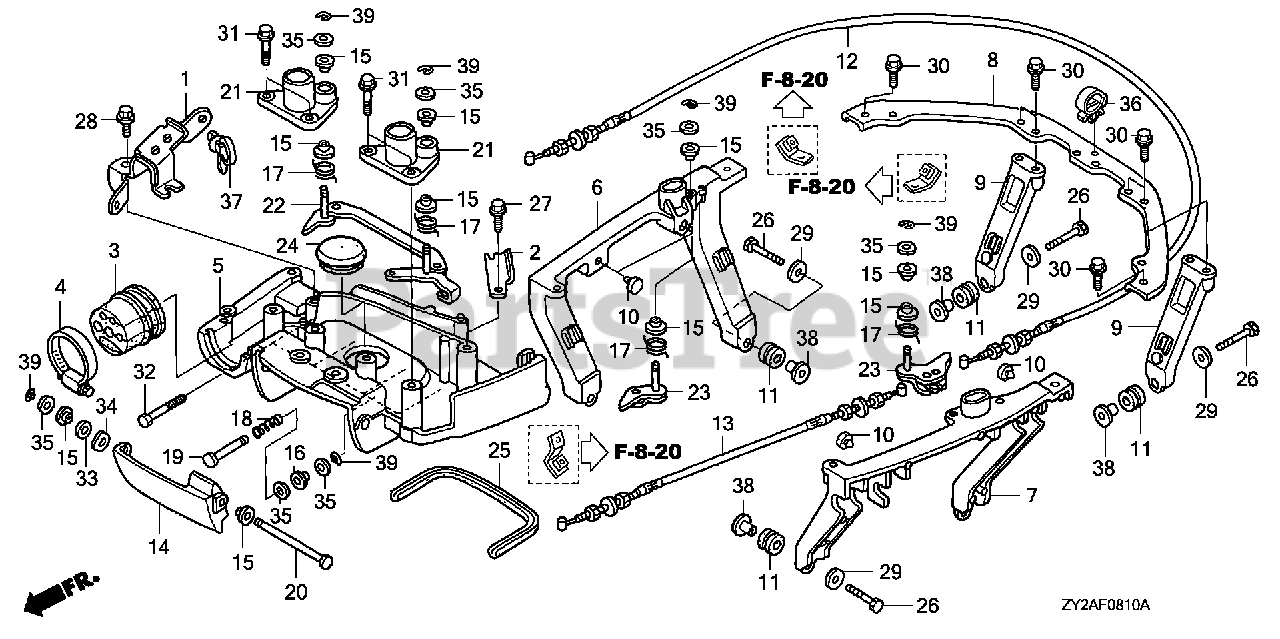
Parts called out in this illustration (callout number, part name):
1	BRACKET, CABLE
2	PLATE, STARTER CABLE
3	GROMMET A, CASE (LOWER)
4	BAND, CASE GROMMET (LOWER)
5	BRACKET, FR. COVER *NH8* (DARK GRAY)
6	BRACKET, R. SIDE COVER
7	BRACKET, L. SIDE COVER
8	BRACKET A, RR. COVER
9	BRACKET B, RR. COVER
10	RUBBER, STOPPER
11	RUBBER, FR. CARRIER CUSHION
12	CABLE A, COVER LOCK
13	CABLE B, COVER LOCK
14	LEVER, COVER LOCK *NH282MU* (OYSTER SILVER METALLIC-U)
15	BUSH A, COVER LOCK
16	BUSH B, COVER LOCK
17	SPRING, COVER LOCK HOOK
18	SPRING, LOCK LEVER RETURN
19	SHAFT, COVER OPEN
20	SHAFT, FR. LOCK
21	HOLDER, STRIKER
22	LOCK ASSY., FR.
23	LOCK, SIDE
24	CAP, L. SIDE COVER
25	SEAL D, COVER (LOWER)
26	BOLT, HEX. (8X35)
27	BOLT, FLANGE (6X14)
28	BOLT, FLANGE (6X14)
29	WASHER, PLAIN (8MM)
30	BOLT, FLANGE (6X12)
31	BOLT, FLANGE (6X20)
32	BOLT, FLANGE (8X22)
33	WASHER, PLAIN (10MM)
34	WASHER, WAVE (10MM)
35	WASHER, PLAIN (8MM)
36	CLIP, HARNESS
37	CLIP, HARNESS BAND (145MM) (BLACK)
38	COLLAR (8.5X14.5)
39	E-RING (6MM)
